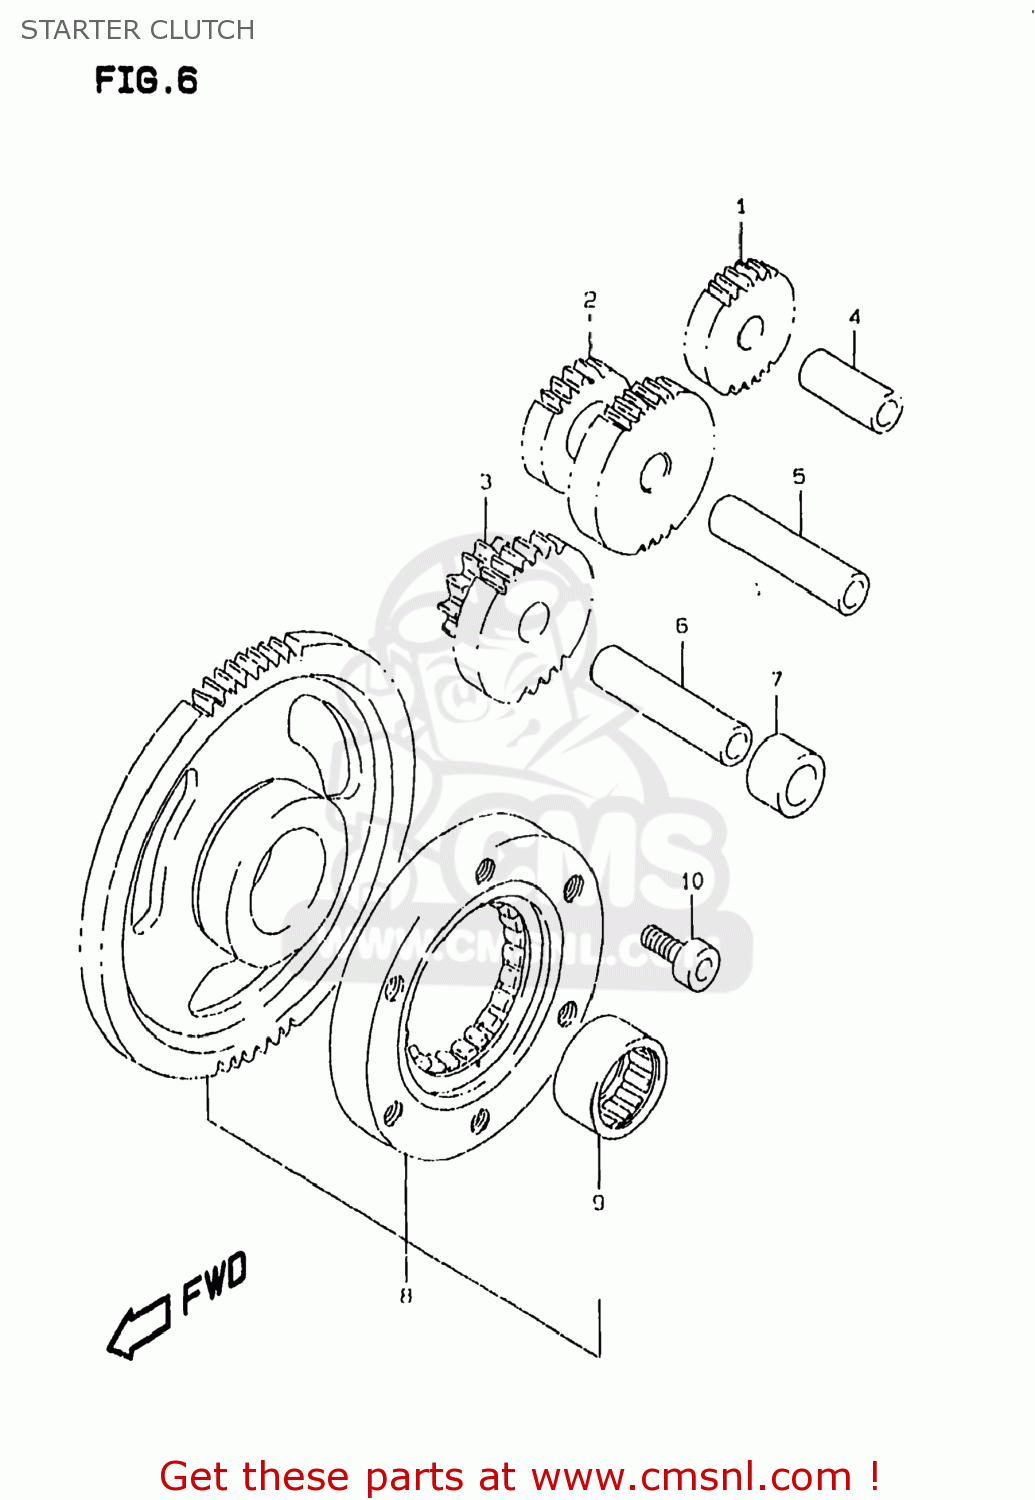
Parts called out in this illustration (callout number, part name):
1	GEAR,STARTER IDLE NO.1(NT:34)
2	GEAR,STRTR IDLE NO.2(NT:22/47)
3	GEAR,STARTER IDLE NO.3
4	PIN(6X10X32)
5	PIN(6X10X55.5)
6	PIN(12X55.5)
7	SPACER(12.5X19X13)
8	CLUTCH SET,STARTER
9	BEARING(29X36X18)
10	BOLT
